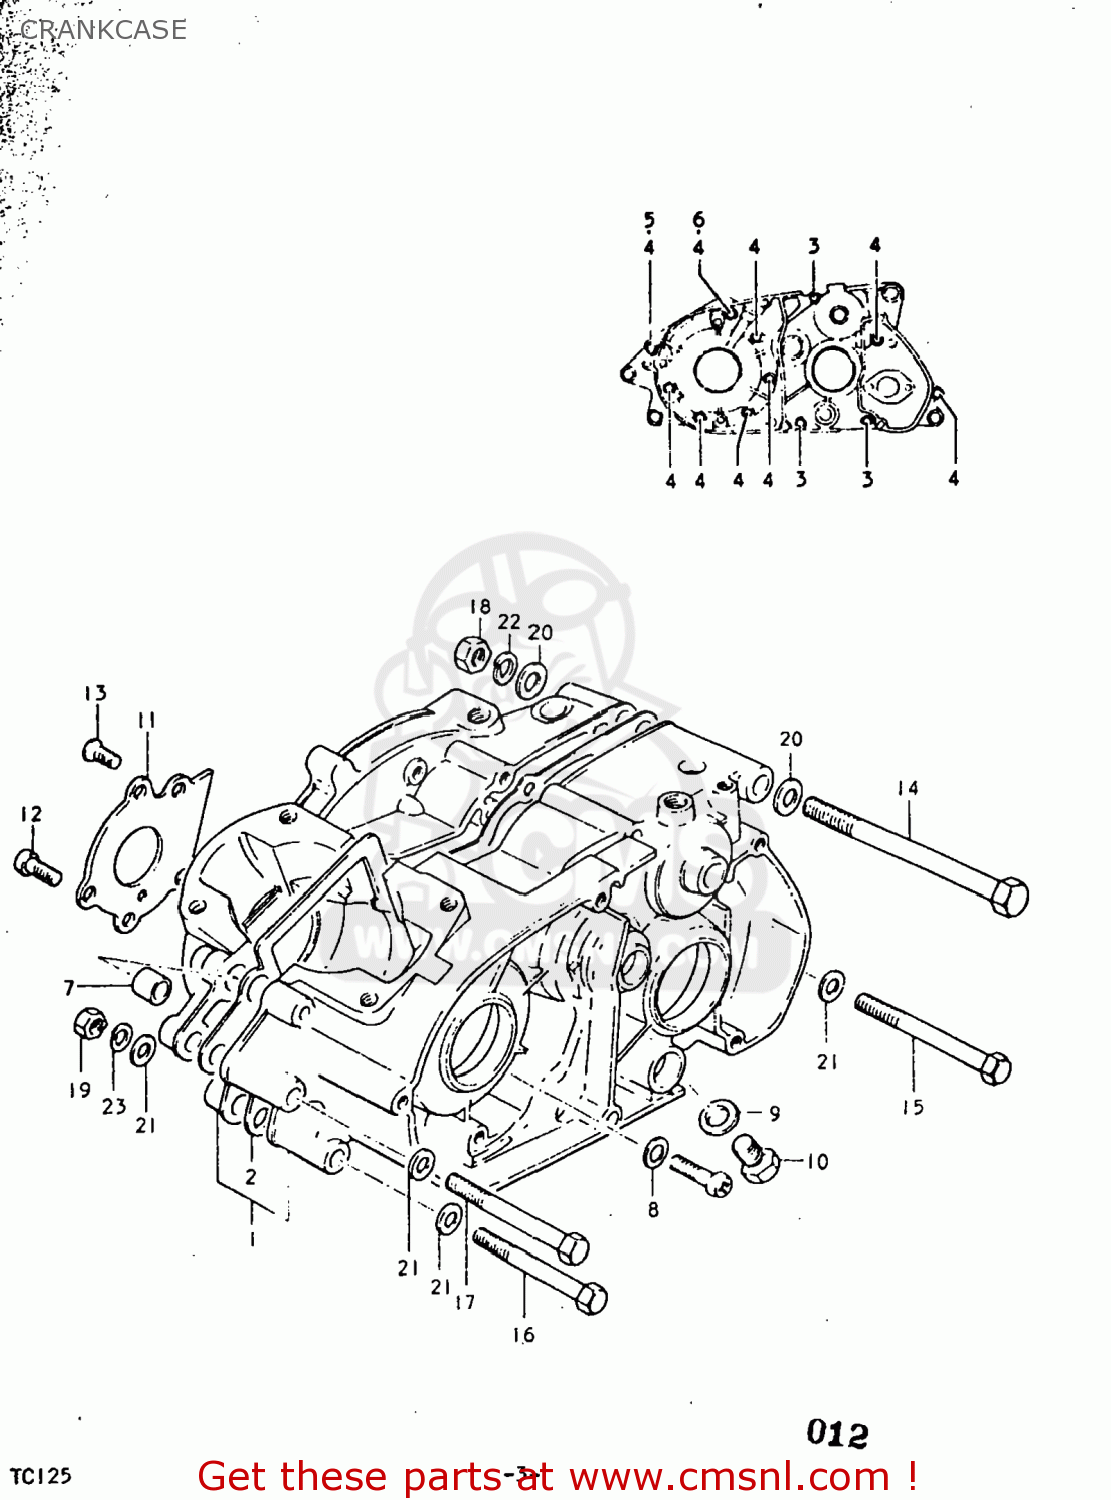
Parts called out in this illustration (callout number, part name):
1	CRANKCASE SET
2	GASKET,CRANKCASE (MCA)
3	SCREW
4	SCREW (6X45)
5	SCREW 6X80
6	SCREW 6X60
7	PIN
8	WASHER 6MM
9	GASKET(14X19.2X2) (NAS)
10	PLUG
11	PLATE,OIL RESERVOIR
12	SCREW
13	SCREW
14	BOLT 10X120
15	HEXAGON BOLT 8X80
16	BOLT,8X75
17	BOLT
18	NUT
19	NUT
20	WASHER
21	WASHER
22	LOCK WASHER
23	LOCK WASHER
